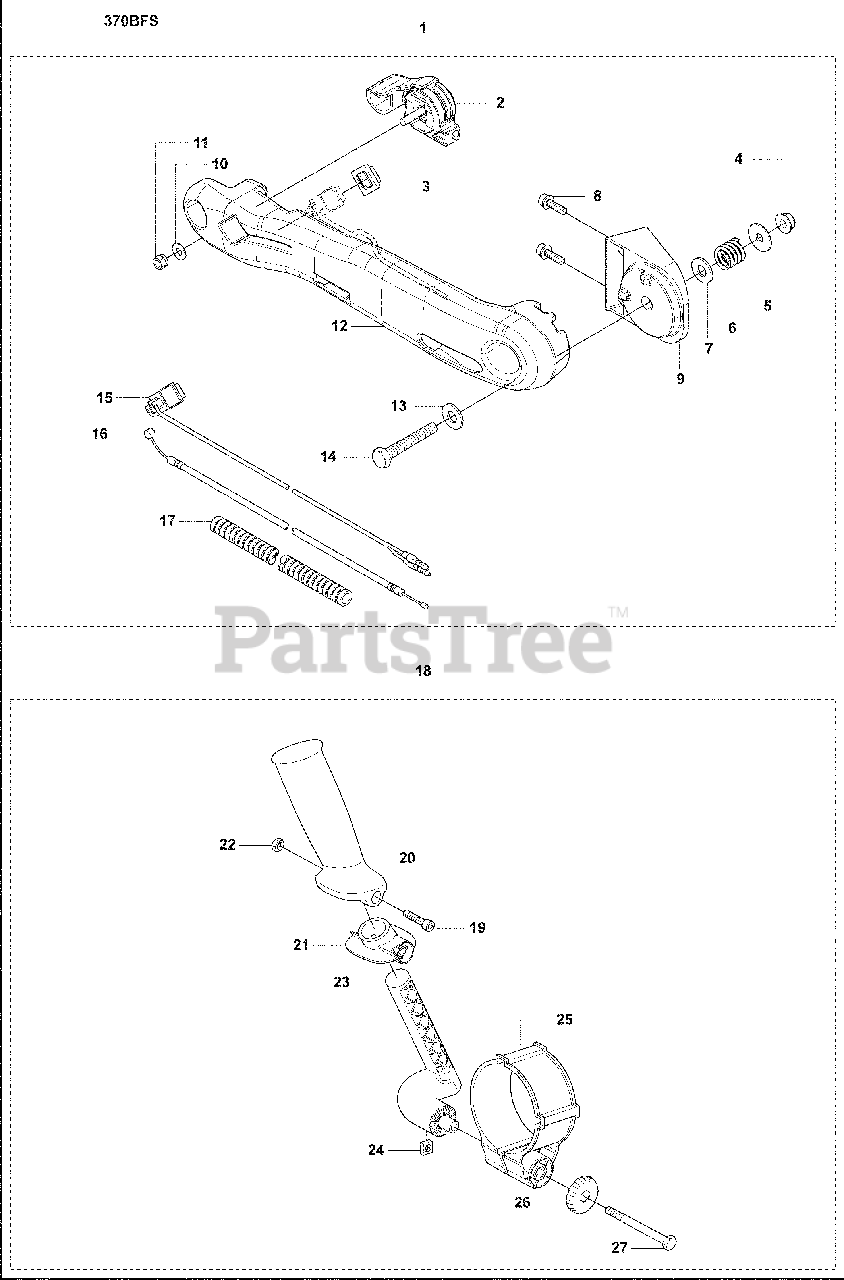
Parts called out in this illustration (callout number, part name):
1	Handle Assembly
2	Lever
3	Switch Cap
4	Nut
5	Washer
6	Spring
7	Washer
8	Screw
9	Bracket
11	Nut
12	ARM
13	Washer
14	Bolt
16	Cable, Complete
19	Screw
22	Hex Nut, M5 X .80 DIN
23	Holder
24	Square Nut
25	HOLDER TH
26	Air Filter Cover Knob
